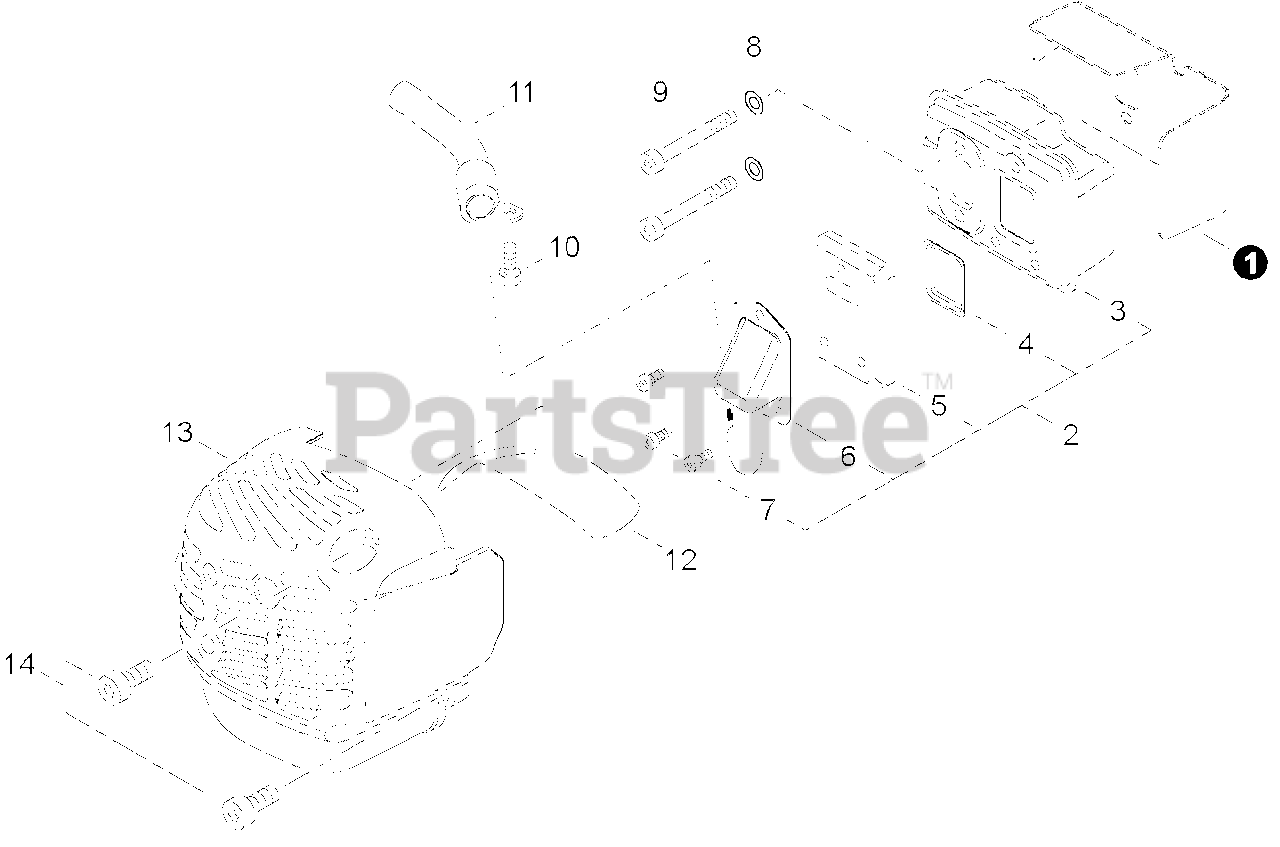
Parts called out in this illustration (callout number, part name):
1	SHIELD, EXHAUST
2	MUFFLER ASSY
3	MUFFLER
4	SCREEN, SPARK ARRESTOR
5	GASKET, EXHAUST
6	GUIDE, EXHAUST
7	SCREW - 4X8
8	WASHER - 5
9	SCREW - 5X55
10	SCREW - 5X10
11	GUIDE, EXHAUST
12	PLATE, INSULATOR
13	COVER, MUFFLER
14	SCREW - 5X16
